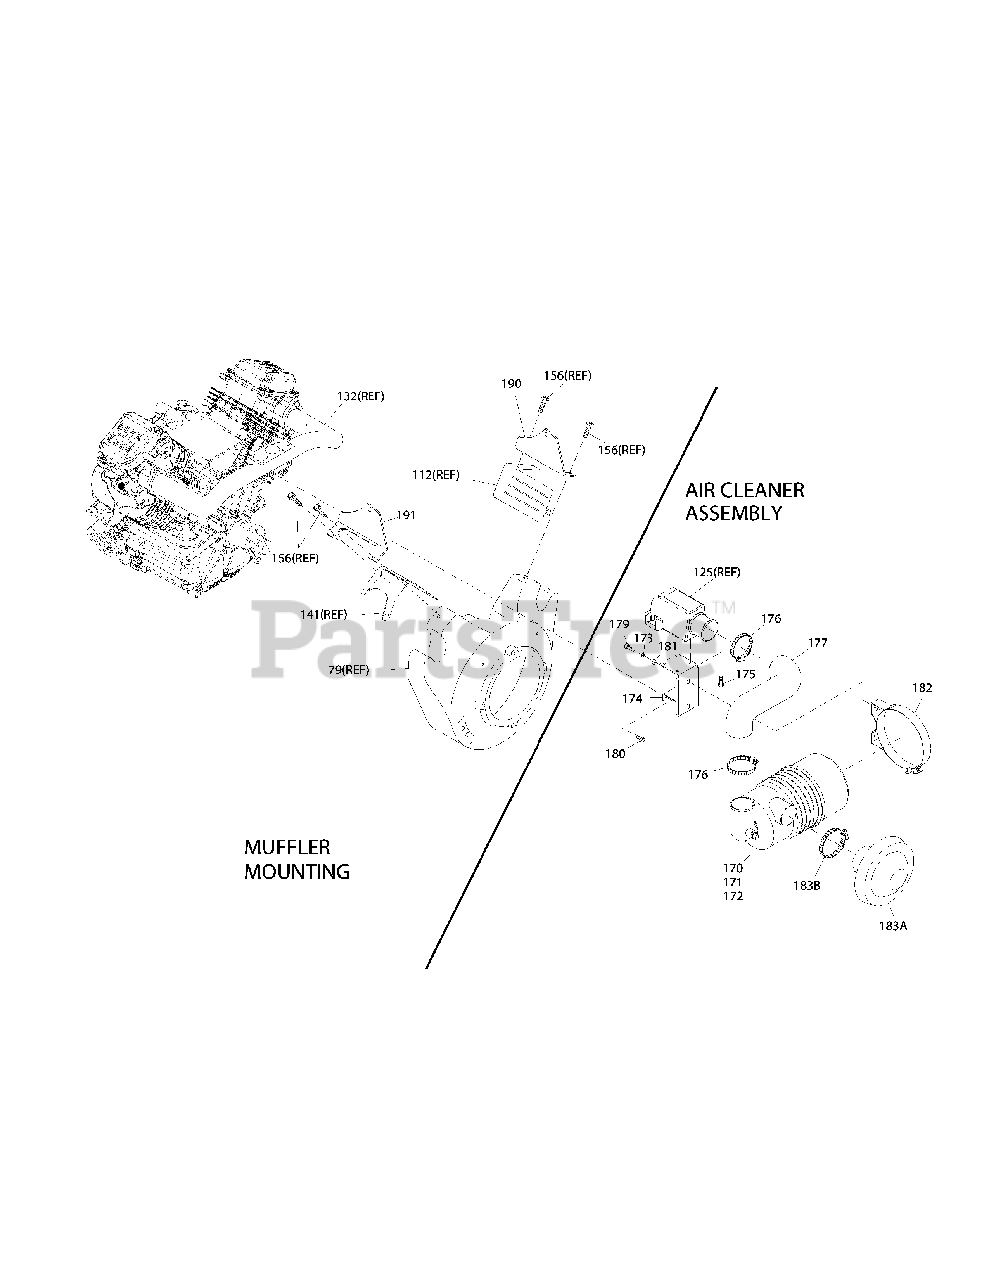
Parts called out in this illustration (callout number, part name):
170	CLEANER, AIR W/SFTY FLT
173	WASHER LOCK M8-5/16
174	BRKT, AIR CLEANER SUPPORT
175	SCREW BHSC M6-1.0 X 12 SS
176	CLAMP HOSE #32 1.563-2.500
177	HOSE AIR CLEANER
179	SCREW HHC M8-1.25 X 16 G8.8
180	SCREW HHFC M6-1.0 X 10 G8.8
181	WASHER FLAT 5/16-M8 ZINC
182	ASSY, BAND MOUNT AIR CLEANER
183A	HOOD, INLET
183B	CLAMP, HOSE
190	SUPPORT, MUFFLER LH
191	SUPPORT, MUFFLER RH
